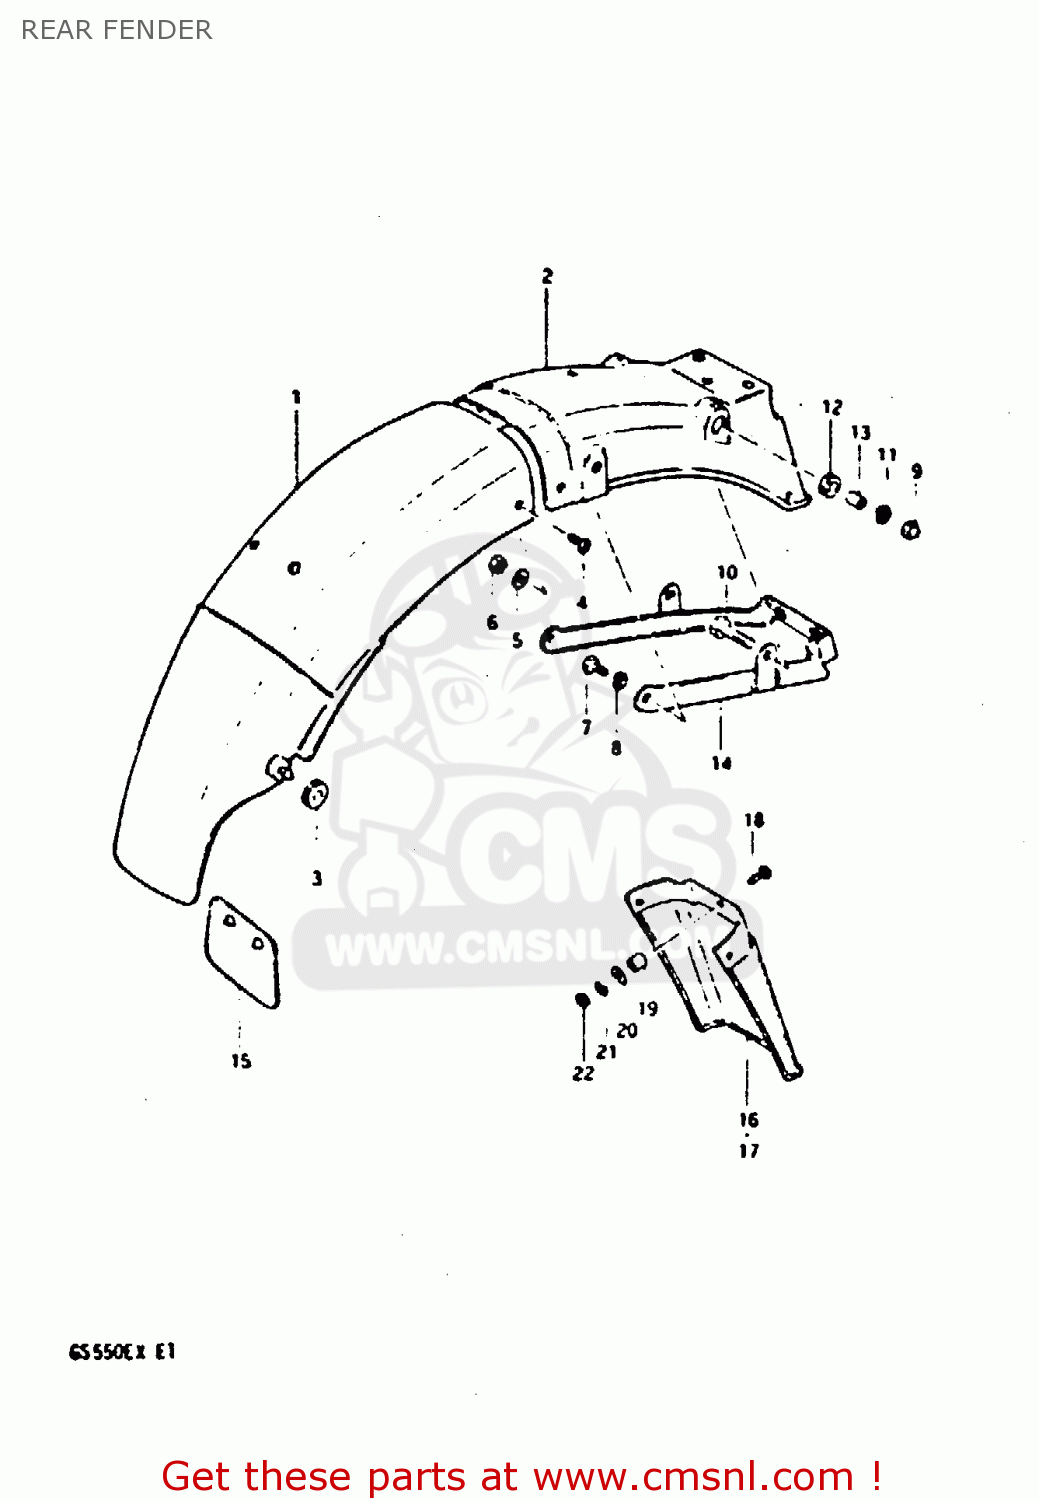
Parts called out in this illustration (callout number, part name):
1	BODY,RR FENDER FR
2	BODY,REAR FENDER,REAR
3	CUSHION
4	SCREW
5	WASHER (5.5X16X1.2)
6	NUT
7	BOLT, UPPER
8	LOCK WASHER
9	NUT
10	BOLT
11	LOCK WASHER
12	CUSHION
13	SPACER (8.2X12X7.5)
14	REINFORCEMENT,REAR FENDER
15	GUIDE,RR FENDER MUD
